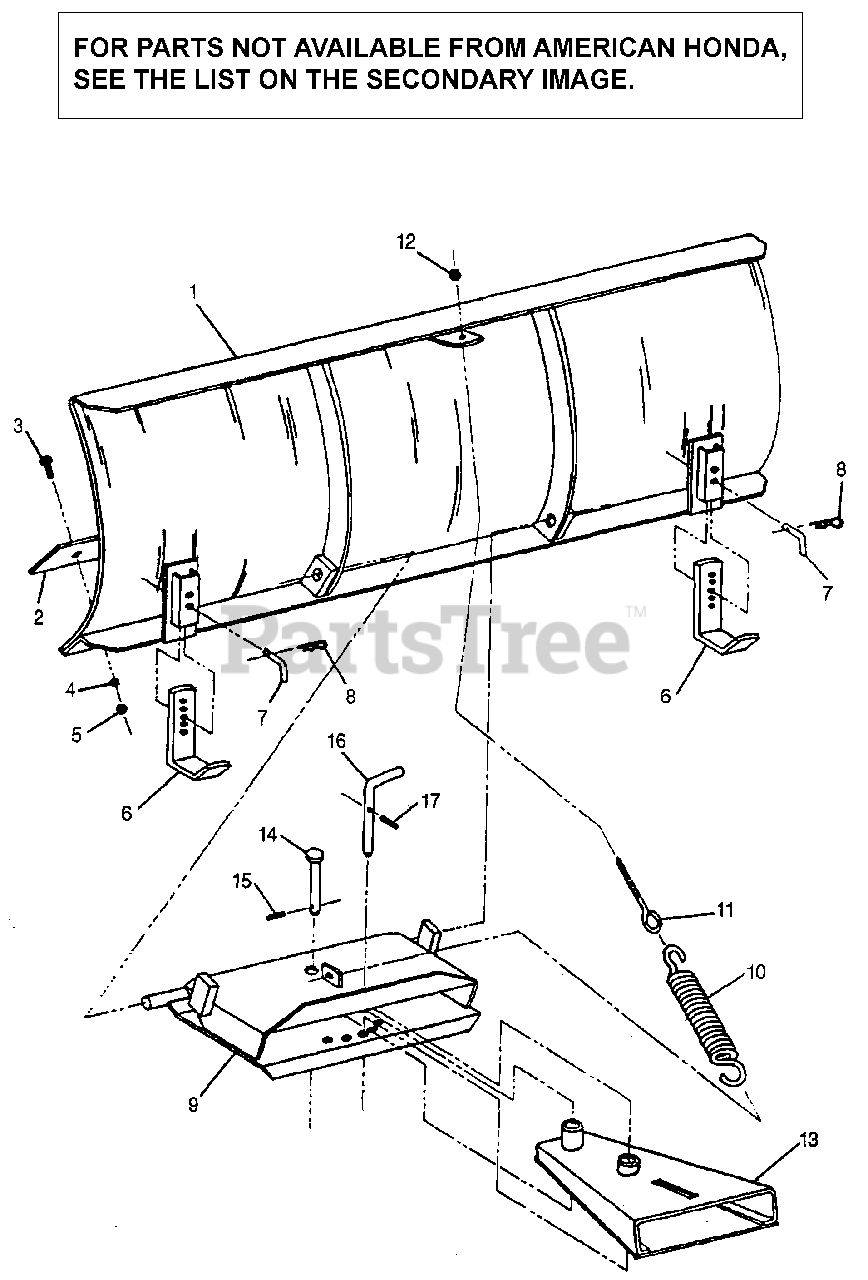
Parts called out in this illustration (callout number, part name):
2	CUTTING EDGE (46")
2	CUTTING EDGE (54")
6	SHOE, SKID
7	PIN, SKID SHOE
9	HITCH BOX (46")
9	HITCH BOX (54")
10	SPRING, TENSIONER
11	BOLT, EYE (5/16"NCX5")
13	FEMALE HITCH
14	PIN, ADJUSTMENT
16	PIN, PIVOT
16	PIN, ADJUSTMENT (54")
18	PIN (3/4"DIAX18")
